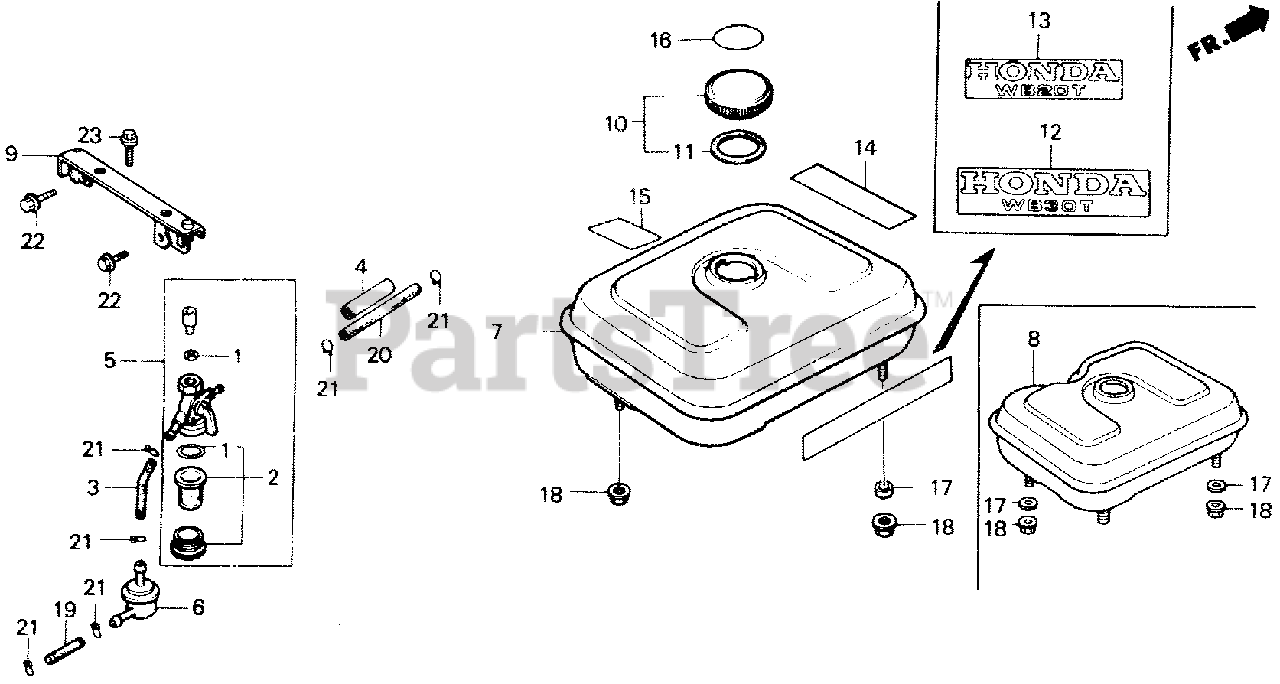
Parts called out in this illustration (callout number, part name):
1	GASKET SET, PETCOCK
2	CUP, FUEL STRAINER
2	CUP SET, FUEL STRAINER
3	TUBE, FUEL
4	RUBBER, SUPPORTER
5	PETCOCK ASSY.
6	FILTER, FUEL
7	TANK, FUEL *NH31* (MCKINLEY WHITE)
9	STAY, FUEL TANK
10	CAP, FUEL FILLER (BLACK)
11	GASKET, FUEL FILLER CAP (39X58X3)
12	MARK (WB30T)
14	MARK, CAUTION (PUMP)
15	LABEL, PUMP WARNING
16	MARK, CAUTION
17	COLLAR, TANK SETTING
18	NUT, FLANGE (6MM)
19	BULK HOSE, FUEL (4.5X3000) (4.5X25)
20	BULK HOSE, FUEL (4.5X3000) (4.5X120)
21	CLIP, TUBE (B8)
22	BOLT, FLANGE (6X14)
23	BOLT, FLANGE (6X28)
